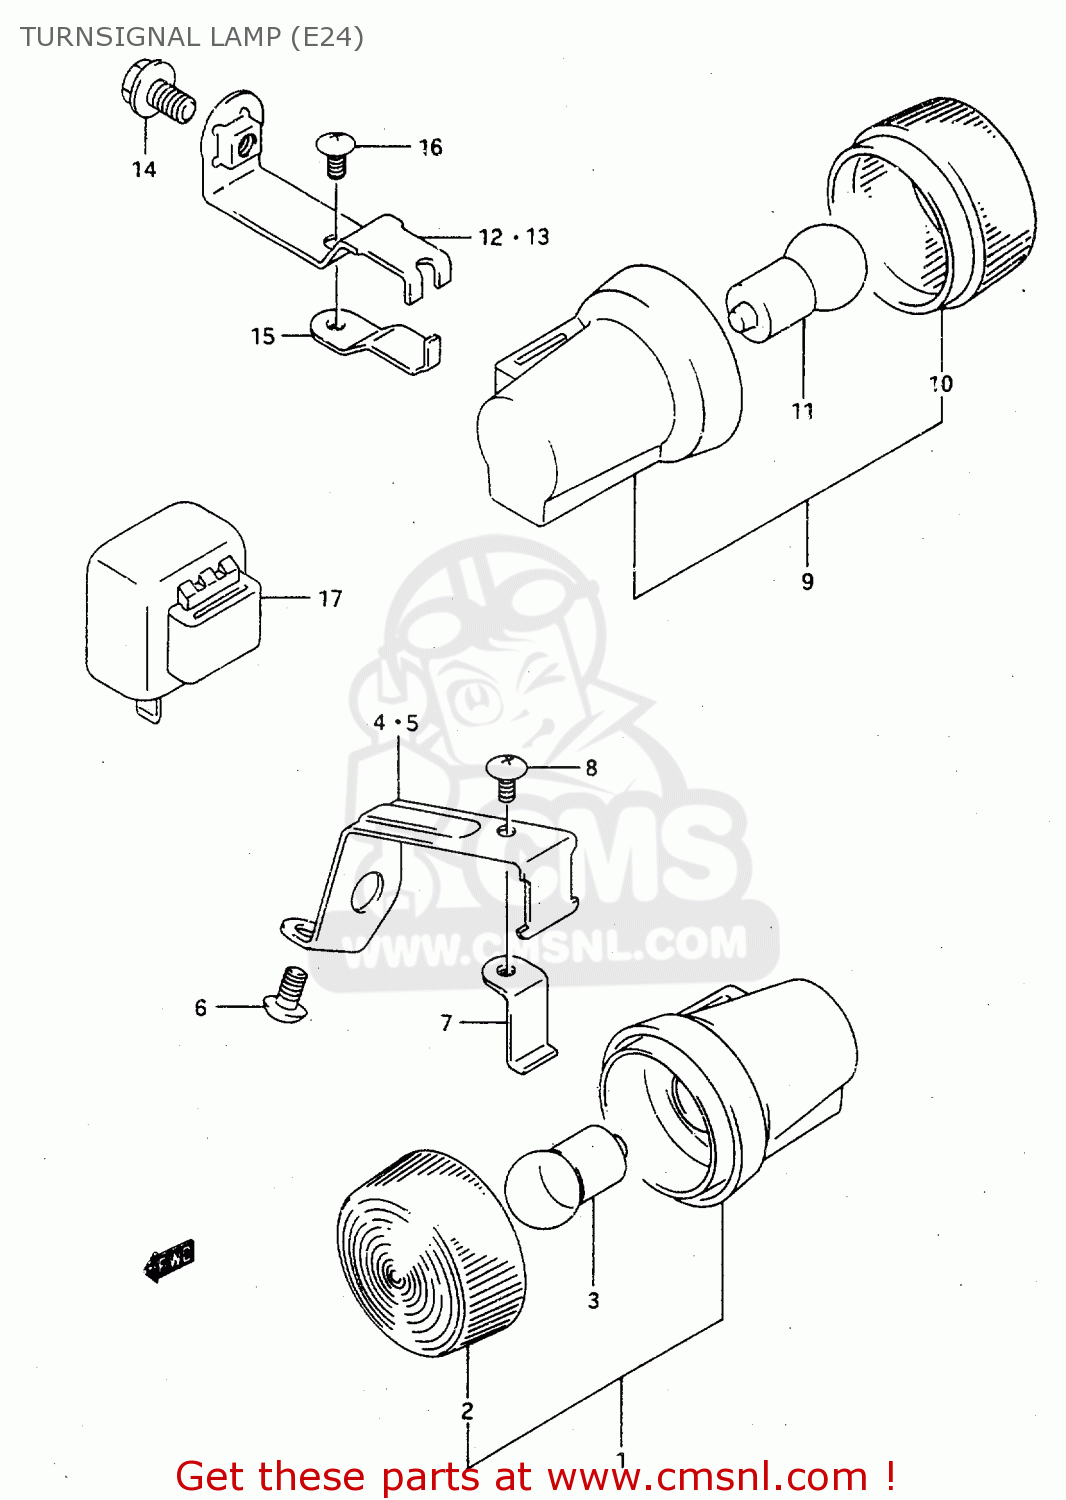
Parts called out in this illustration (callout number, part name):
1	LAMP ASSY, FRONT TURNSIGNAL, RH
2	LENS
3	BULB 12V 10W
4	BRACKET, FRONT TURNSIGNAL,RH
5	BRACKET, FRONT TURNSIGNAL,LH
6	SCREW
7	PLATE,FR TURNSIGNAL BRACKET
8	SCREW
9	LAMP ASSY, REAR TURNSIGNAL,RH
10	LENS
11	BULB 12V 10W
12	BRACKET,RR TURNSIGNAL LAMP,R
13	BRACKET,RR TURNSIGNAL LAMP,L
14	BOLT
15	PLATE,RR TURN SIGNAL
16	SCREW
17	RELAY, TURNSIGNAL
